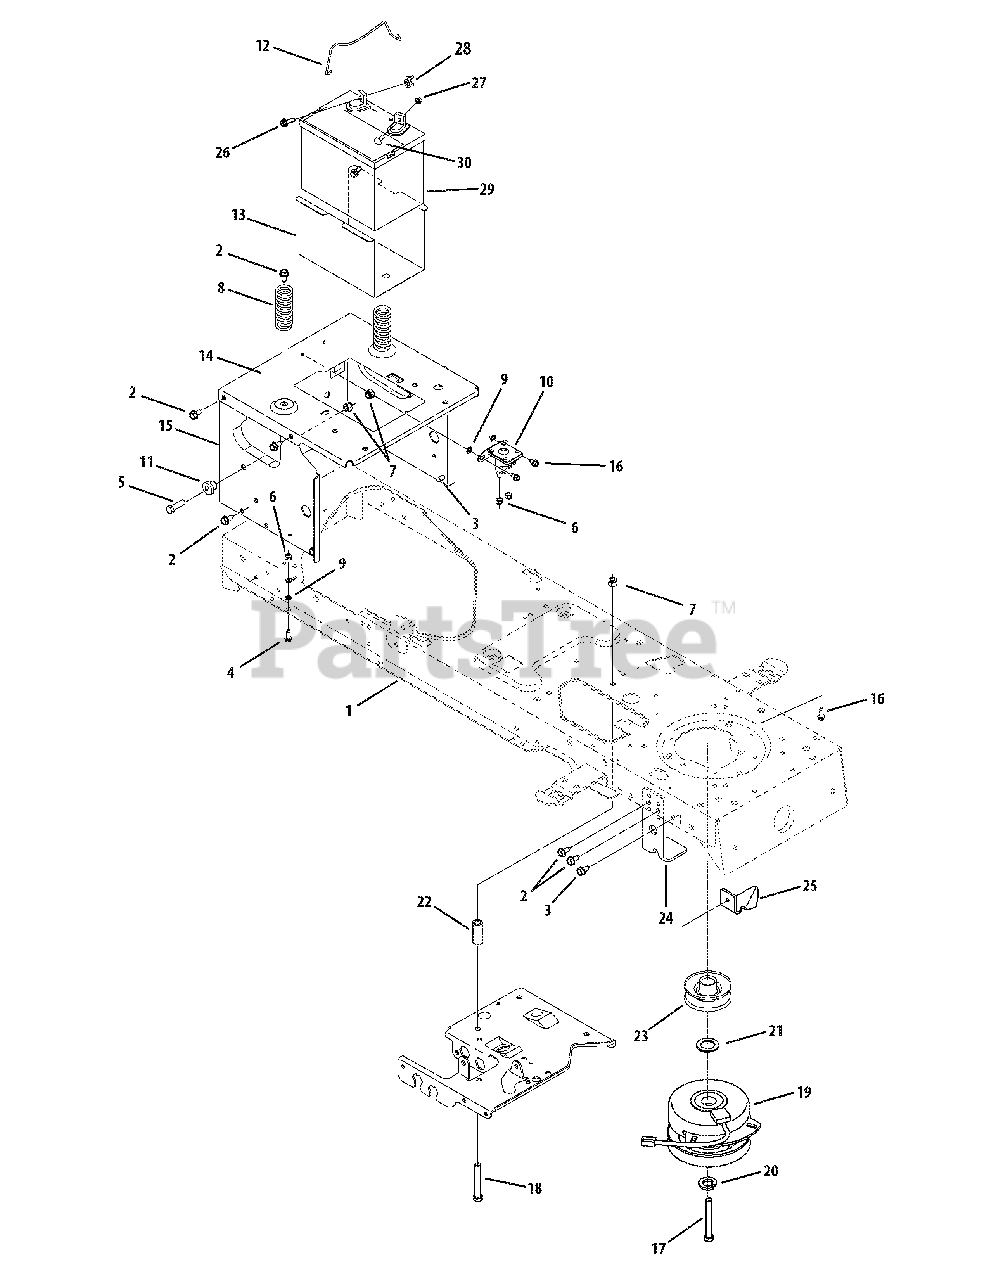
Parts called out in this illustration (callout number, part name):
3	Screw, 5/16-18, 0.500
4	Screw, 1/4-20, 0.750
5	Screw, 3/8-16, 1.25, Gr5
6	Nut, Flange Lock, 1/4-20
7	Nut, Flange Lock, 3/8-16
8	Spring, Compress., 1.28 x 3.125
9	Washer, Lock, 1/4, External
10	Solenoid, 12V, 100 Amp
11	Spacer, Shoulder,.38 x 1.0 x.70
12	Hold Rod, Battery
16	Screw, 1/4-20, 0.50
17	Screw, 7/16-20, 3.50, Gr5, Lock
18	Screw, 3/8-16, 2.25, Gr5
19	PTO Clutch, Electric
20	Lock Washer, 7/16
21	Washer, Flat, 1.031 x 1.620 x.095
22	Spacer,.385 ID x.635 OD x 1.54
23	Pulley, Engine, 3.56 Diameter
26	Hex Flange Bolt, 1/4-20,.75
27	Nut, Sems, 1/4-20
28	Wing Nut, 1/4-20
29	Battery, 235 CCA
30	Shoulder Screw, 1/4-20
